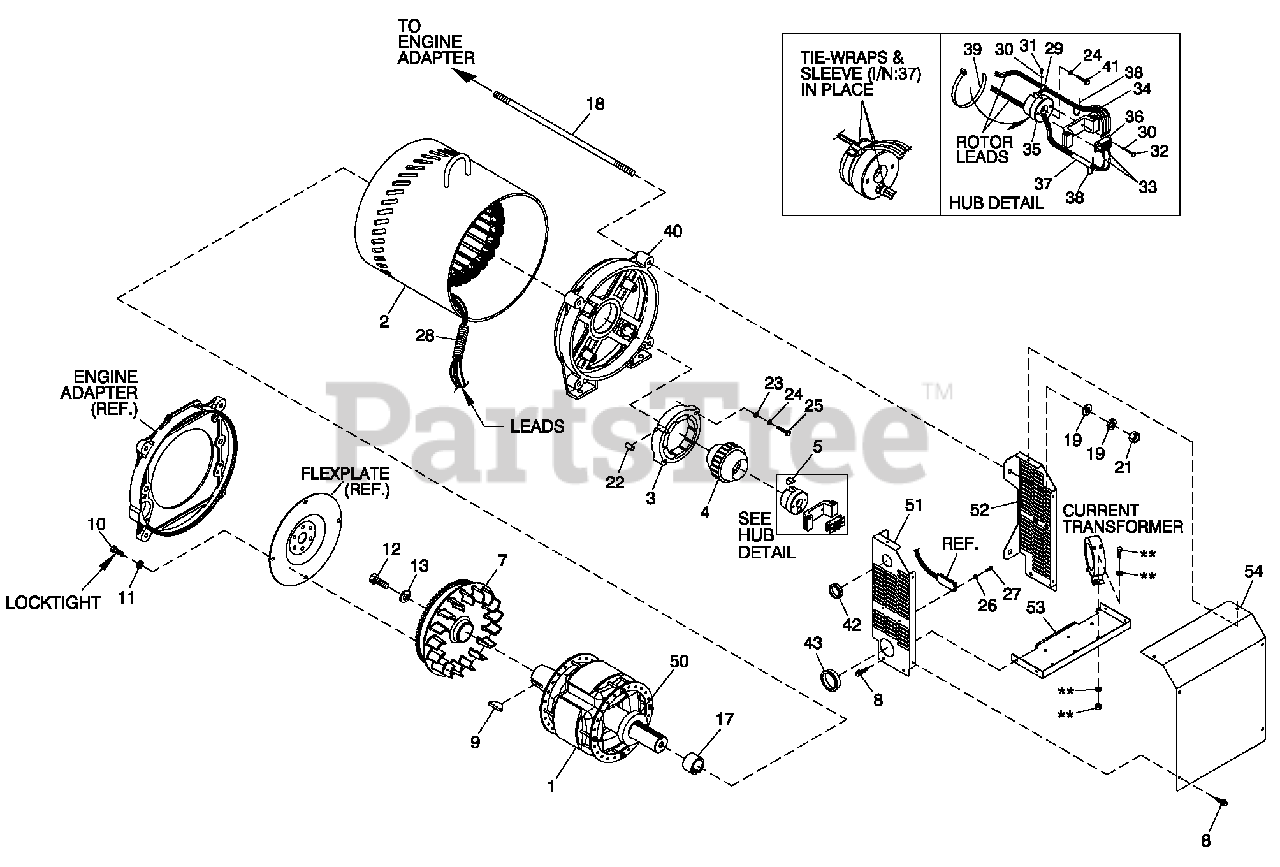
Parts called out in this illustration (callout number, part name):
1	ROTOR 390 70AB3 CPL
2	STATOR 390 70AB3 CPL
3	EXITER FIELD 2" LG SPD CONN
4	ASSY EXCITER 2.00" STK
5	KEY SQ 3/8 X 3-1/4 STEEL
7	ASSY FLYWHEEL CPL
8	SCREW THF M6-1 X 16 N WA Z/JS
9	KEY WOODRUFF #E
10	SCREW HHC M10-1.50 X 16 G10.9
11	WASHER LOCK M10
12	SCREW HHC M16-2.0X 45 G8.8
13	SPACER .69 X 2.75 X .37 ST/ZNC
14	WASHER FLAT 1/4-M6 ZINC
15	WASHER LOCK M6-1/4
16	SCREW HHC M6-1.0X 16 G8.8
17	COLLAR SLIP FIT 390 MM
18	STUD M14-2.0X 650 G5 ZINC
19	WASHER FLAT M14
20	WASHER LOCK M14
21	NUT HEXM14-2.0G8YEL CHR
22	PIN DOWEL 1/2 X 1-1/4
23	WASHER FLAT M12
24	WASHER LOCK M12
25	SCREW HHC M12-1.75 X 80 G10.9
26	SCREW PHTT #6-32 X 1/2 ZYC
27	WASHER LOCK #6
28	CONDUIT FLEX 1.25" ID
29	CLAMP VINYL .312X.203Z
30	WASHER SHAKEPROOFINT #8
31	SCREW HHM #8-32X3/8
32	SCREW HHM #8-32X7/8
33	LUGRT-ANG #10/10-12
34	BRIDGE SUPPORT DIODE 15"
35	CAP END ROTOR 390MM
36	ASSY BRIDGE RECTIFIER
37	SLEEVING UL #0.330 ID (3" LG)
38	TIE WRAP UL 3.9" X .10" BLK
39	TIE WRAP UL 17.7 X .35 BLK HT
40	REAR BEARING CARRIER CPL
41	SCREW HHC M12-1.75 X 60 G10.9
42	BUSHING SNAP SB-1750-22
43	BUSHING SNAP SB-2.5-31
50	BEARING BALL 6212 SEALED
51	SIDE LH EXCITER SHIELD
52	SIDE RH EXCITER SHIELD
53	BOTTOM EXCITER SHIELD
54	REAR COVER EXCITER SHLD
